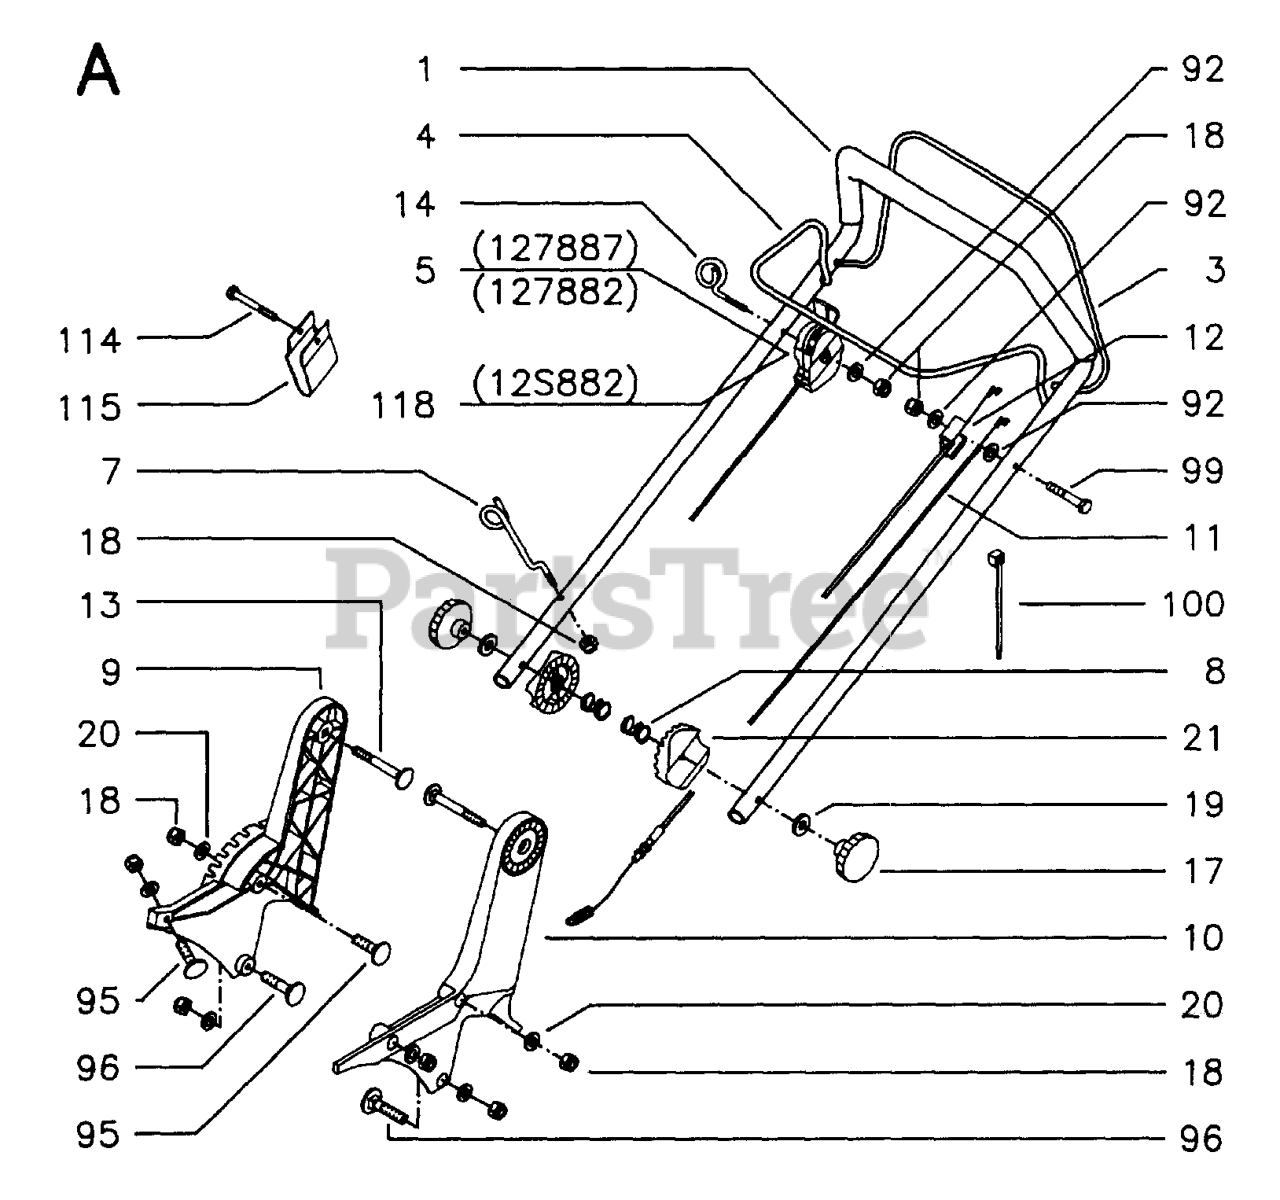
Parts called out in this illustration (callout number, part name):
5	THROTTLE TRIGGER
11	WIRE R 47S/SE
12	WIRE R 47/47S/47SE
18	LOCKNUT M6
95	REPL BY 515 71 16-20
114	SCREW M6X55
118	CONTROL
